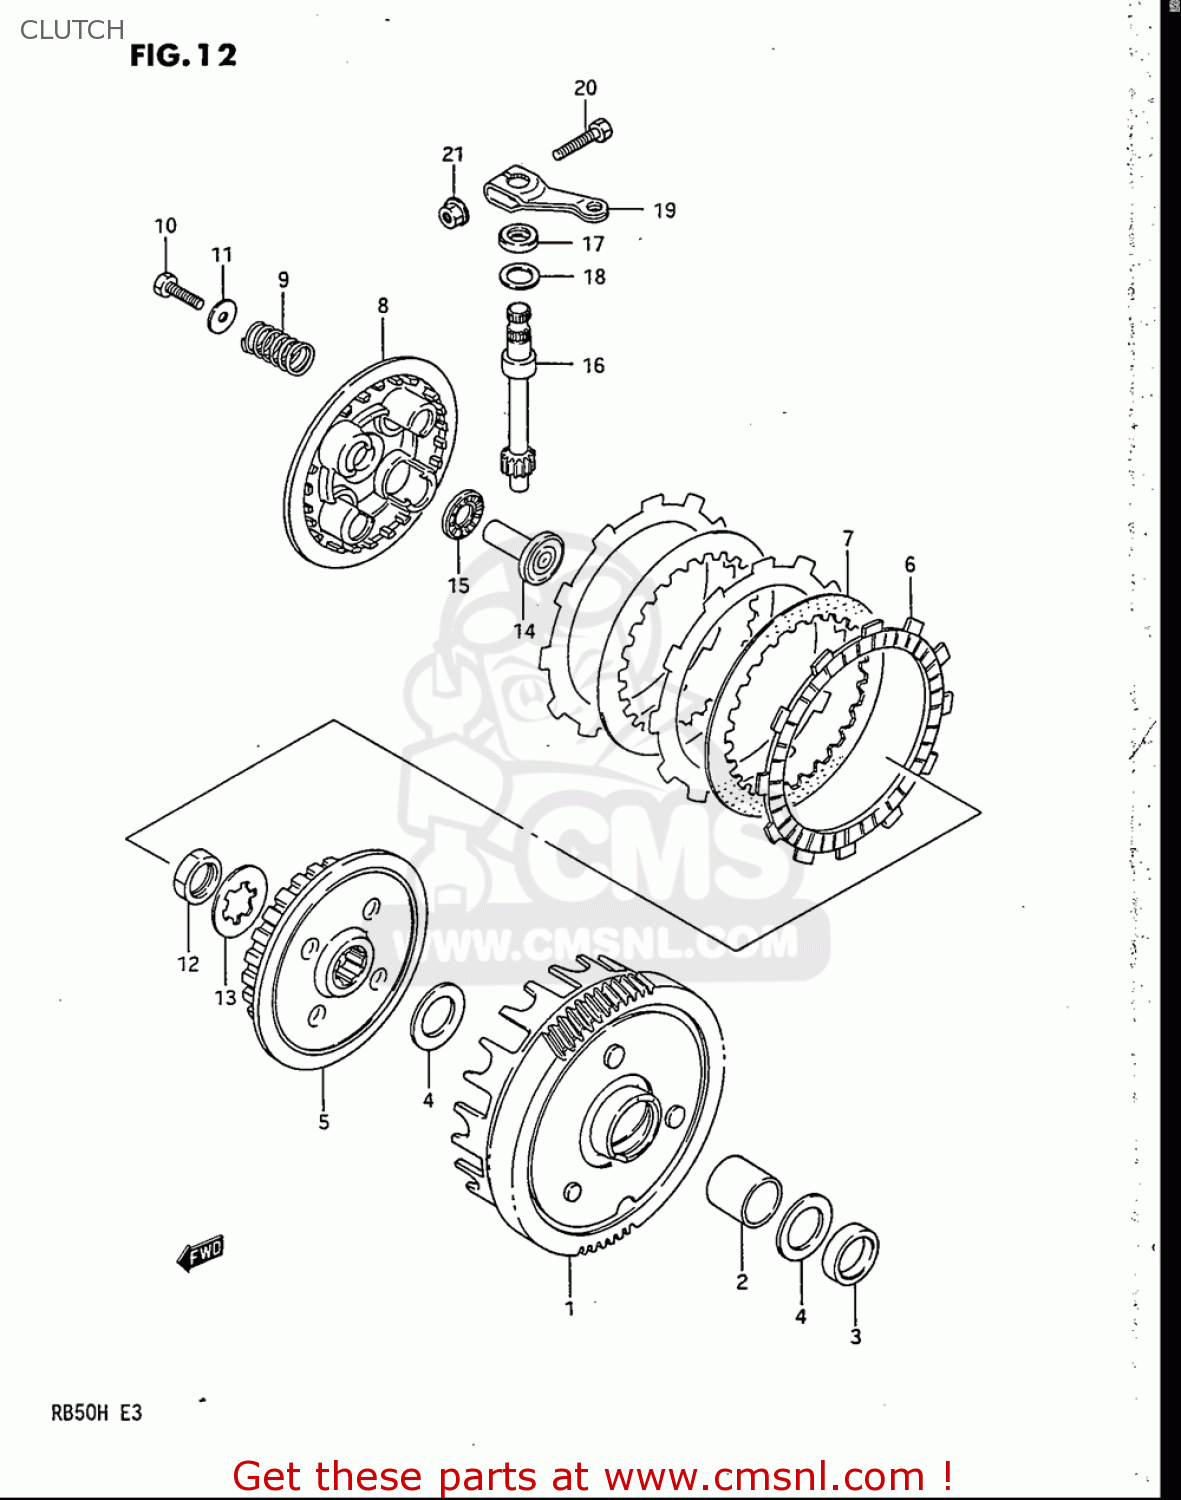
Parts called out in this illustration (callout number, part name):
1	GEAR ASSY,PRI DRIVEN
4	WASHER
5	HUB,CLUTCH SLEEVE
6	PLATE,CLUTCH DRIVE (NAS)
7	PLATE,CLUTCH DRIVEN (NAS)
9	SPRING
10	BOLT(5X16)
11	WASHER(5.5X16X1.2)
12	NUT
13	WASHER,LOCK
14	RACK,CLUTCH RELEASE
15	BEARING(10X22X2.8)
17	SEAL,OIL(10X17X5)
18	WASHER(12.5X17X1)
20	BOLT
21	NUT
